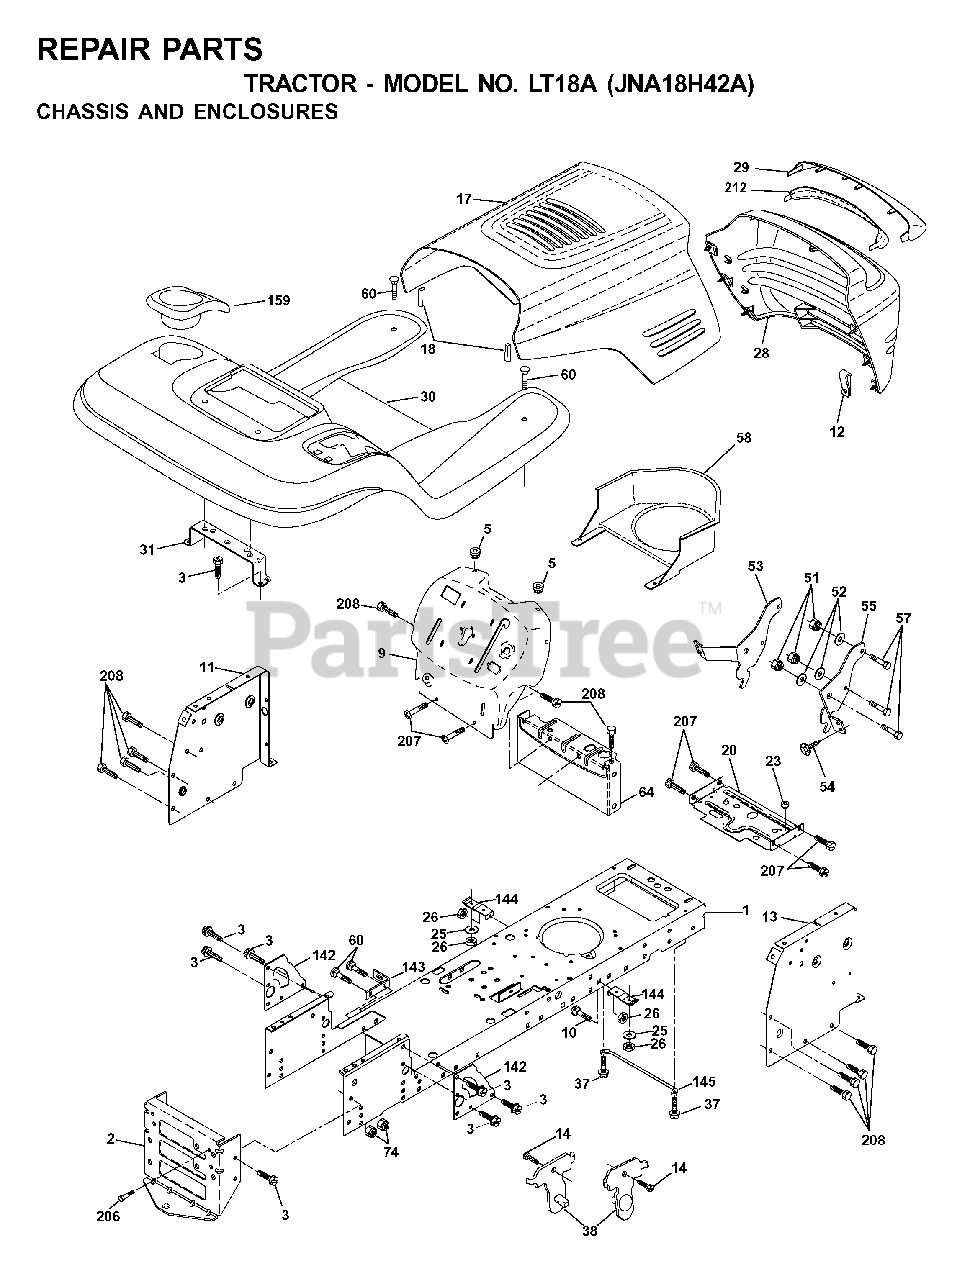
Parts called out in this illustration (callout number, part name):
1	CHASSIS STAMPING
2	DRAWBAR, 12GA
3	SCREW 3/8-16X3/4
5	BUMPER.RUBBER.HOOD
10	BOLT D
11	PANEL DASH LH
13	DASH PANEL RH
14	SCREW LT
18	BUMPER HOOD T
20	PLATE MTG
23	GROMMET T
25	WASHER
26	NUT
30	FENDER, FOOTREST
37	SCREW LT
38	BRACKET.ASM.PIVOT.MOWER.REAR
51	LOCKNUT
52	WASHER
53	BRACKET.GRILLE.LH
57	BOLT
58	DUCT, INTAKE AIR
64	DASH LOWER
74	LOCKNUT
142	PLATE
143	BRACKET, SWAY BAR
144	BRACKET FOOTREST
145	ROD PIVOT CHASSIS/HOOD
206	SHOULDER BOLT 5/16-18TT
207	SCREW, 5/16-18 X 1/2
208	SCREW 3/8-16X1/2
